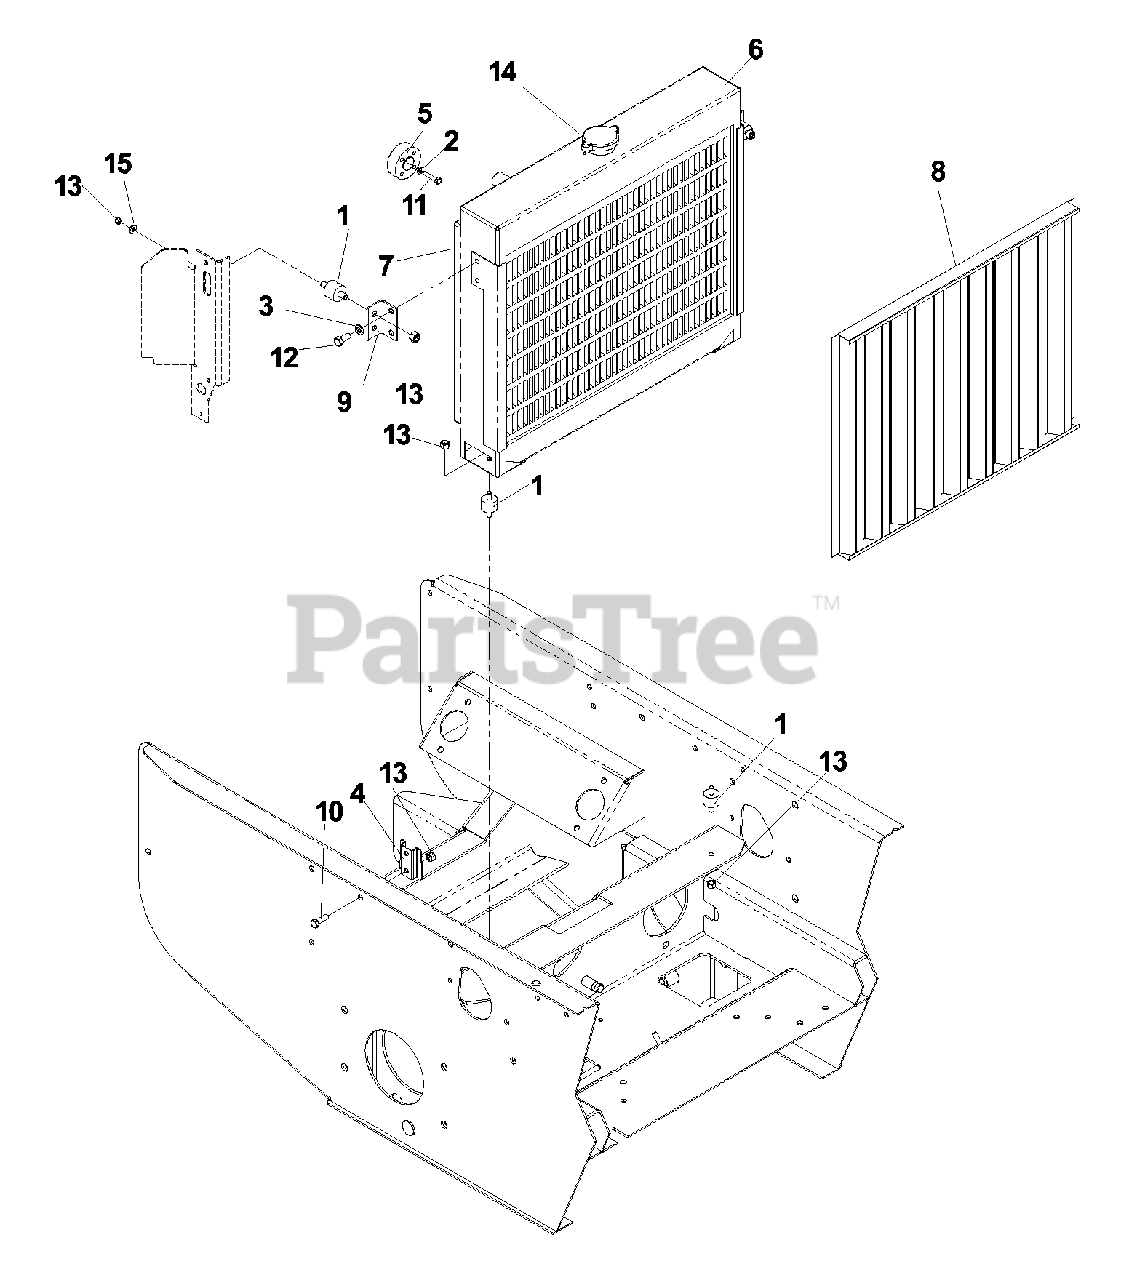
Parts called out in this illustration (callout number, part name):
2	Lockwasher, 1/4
3	Lockwasher, 5/16
4	Bracket, mounting
5	Spacer, fan
8	Debris guard
9	Bracket, isolator
10	Bolt, 5/16-18 x 1
11	Bolt, M6-1 x 40
12	Bolt, 5/16-18 x 3/4
13	Nut, 5/16-18
14	Cap, radiator
15	Washer, 5/16,SAE
